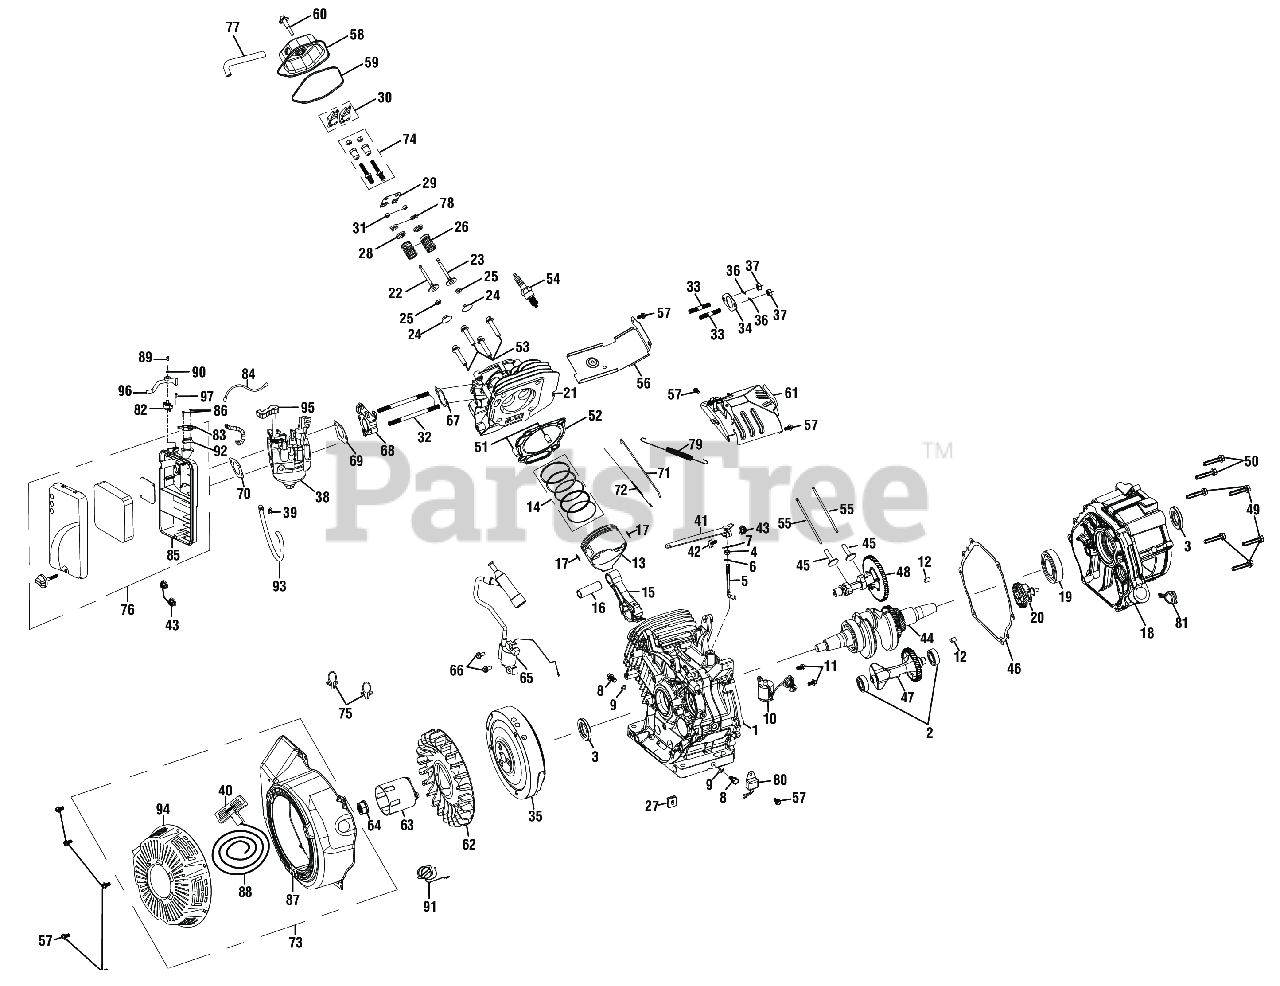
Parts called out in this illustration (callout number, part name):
1	Crankcase
2	Ball Bearing
3	Oil Seal
4	Governor Arm Shaft Seal
5	Governor Arm Shaft
6	Governor Arm Shaft Washer
7	Lock Pin
8	Drain Plug Bolt.
9	Drain Plug Washer
10	Oil Level Switch Assembly
11	Bolt (M6 x 16 mm)
12	Casecover Dowel Pin
14	Piston Scraper Ring Set
15	Connecting Rod Assembly
16	Piston Pin
17	Piston Clip
18	Crankcase Cover Assembly
19	Ball Bearing
20	Governor Assembly
21	Cylinder Head
22	Intake Valve
23	Exhaust Valve
24	Intake Valve Returner
25	Oil Seal Valve
26	Valve Spring
27	Starter Assembly Rubber
28	Exhaust Valve Spring Seat
29	Push Rod Guide Plate
30	Rocker Assembly
32	Stud Bolt
33	Stud Bolt
34	Exhaust Packing
35	Flywheel Assembly
36	Spring Washer
37	Hex Nut (M8)
38	Carburetor Assembly
39	Fuel Line Clip
41	Governor Arm
42	Governor Arm Bolt
43	Hex Nut (M6)
44	Crankshaft Assembly
45	Valve Lifter
46	Casecover Package
47	Balancing Shaft
48	Camshaft Assembly
49	Bolt (M8 x 35 mm)
50	Bolt (M8 x 40 mm)
51	Dowel Pin
52	Cylinder Head Gasket
53	Bolt (M10 x 80 mm)
54	Spark Pulg
55	Push Rod.
57	Bolt (M6 x 12 mm)
58	Cylinder Head Cover Comp
59	Headcover Packing
60	Lock Bolt
61	Upper Shroud Assembly
62	Recoil Starter Fan
63	Starter Pulley
64	Hex Nut (M5)
65	Ignition Coil Assembly
66	Bolt (M6 x 25 mm)
67	Intake Packing
68	Carburetor Insulator
69	Carburetor Packing
70	Carburetor Spacer
71	Governor Rod
72	Throttle Return Spring
73	Recoil Starter Assembly
74	Rocker Arm Adujuster
76	Air Cleaner Assembly
77	Breather Tube
78	Locking Flaps
79	Governor Spring
80	Amplifier
81	Dipstick
82	Fuel Valve
83	Enginge Stop Switch
84	Flameout Wire
85	Air Cleaner Bottom Cover
86	Screw (St 2.9 x 16 mm, Pan Hd)
87	Recoil Starter Assembly
89	Screw (M4 x 10 mm, Phillips Pan Hd.)
91	Switch Assembly
92	Engine Switch Bracket
93	Fuel Hose (330 mm)
94	Recoil cover
95	Choke Lever (Grey)
96	Control Lever (Grey)
97	Screw (M6 x 10 mm, Pan Hd.)
